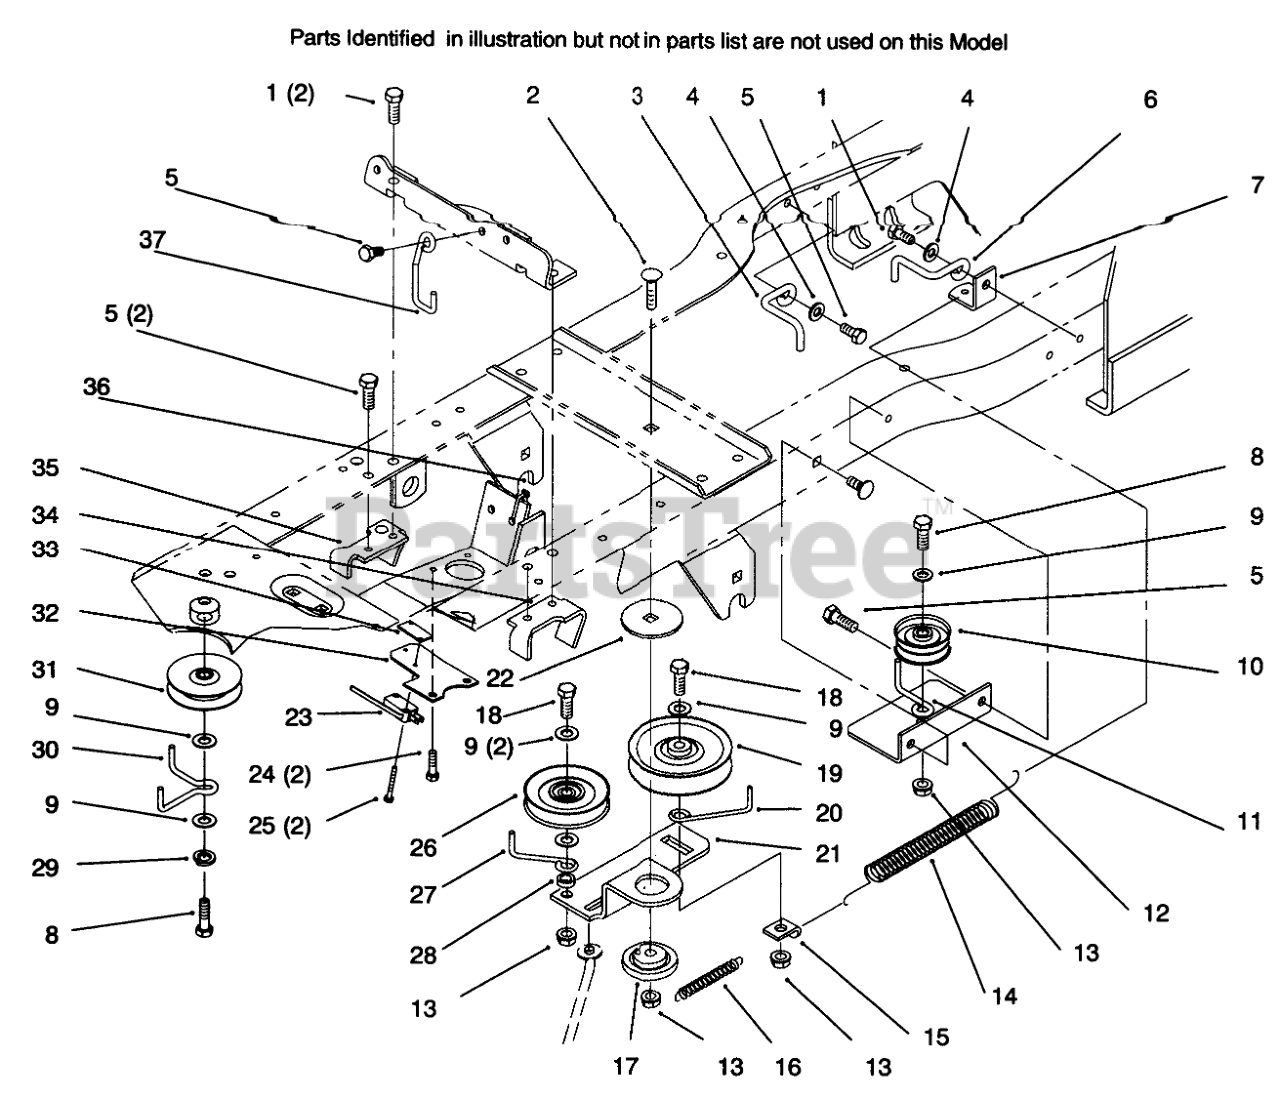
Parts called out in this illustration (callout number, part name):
1	SCREW-HWHTF
2	BOLT-CARR
3	GUIDE - BELT RH
4	WASHER-PLAIN
5	SCREW-HWHTF
6	GUIDE-BELT LH
7	Bracket-Idler Spring
8	SCREW-HH
9	WASHER-FLAT
10	PULLEY IDLER NHI
11	GUIDE-BELT
12	BRACKET-REAR IDLER
13	NUT-LOCK, NI
14	SPRING - CLUTCH
15	CLIP - SPRING
16	SPRING-EXTENSION
17	BUSHING
18	SCREW-HH
19	PULLEY-IDLER, FLAT
20	GUIDE-BELT
21	ARM-IDLER
22	WASHER-BEARING
23	SWITCH-MICRO
24	SCREW-HWH
25	SCREW-HH
26	PULLEY-IDLER
27	GUIDE-BELT
28	Spacer
29	WASHER-LOCK
30	GUIDE-BELT
31	PULLEY-IDLER
32	BRKT-MICROSWITCH GEAR
33	NUT-SPEED
34	CLUTCH PEDAL STOP
35	BRAKE BRACKET PLATED
36	TIE-CABLE
37	GUIDE-BELT
